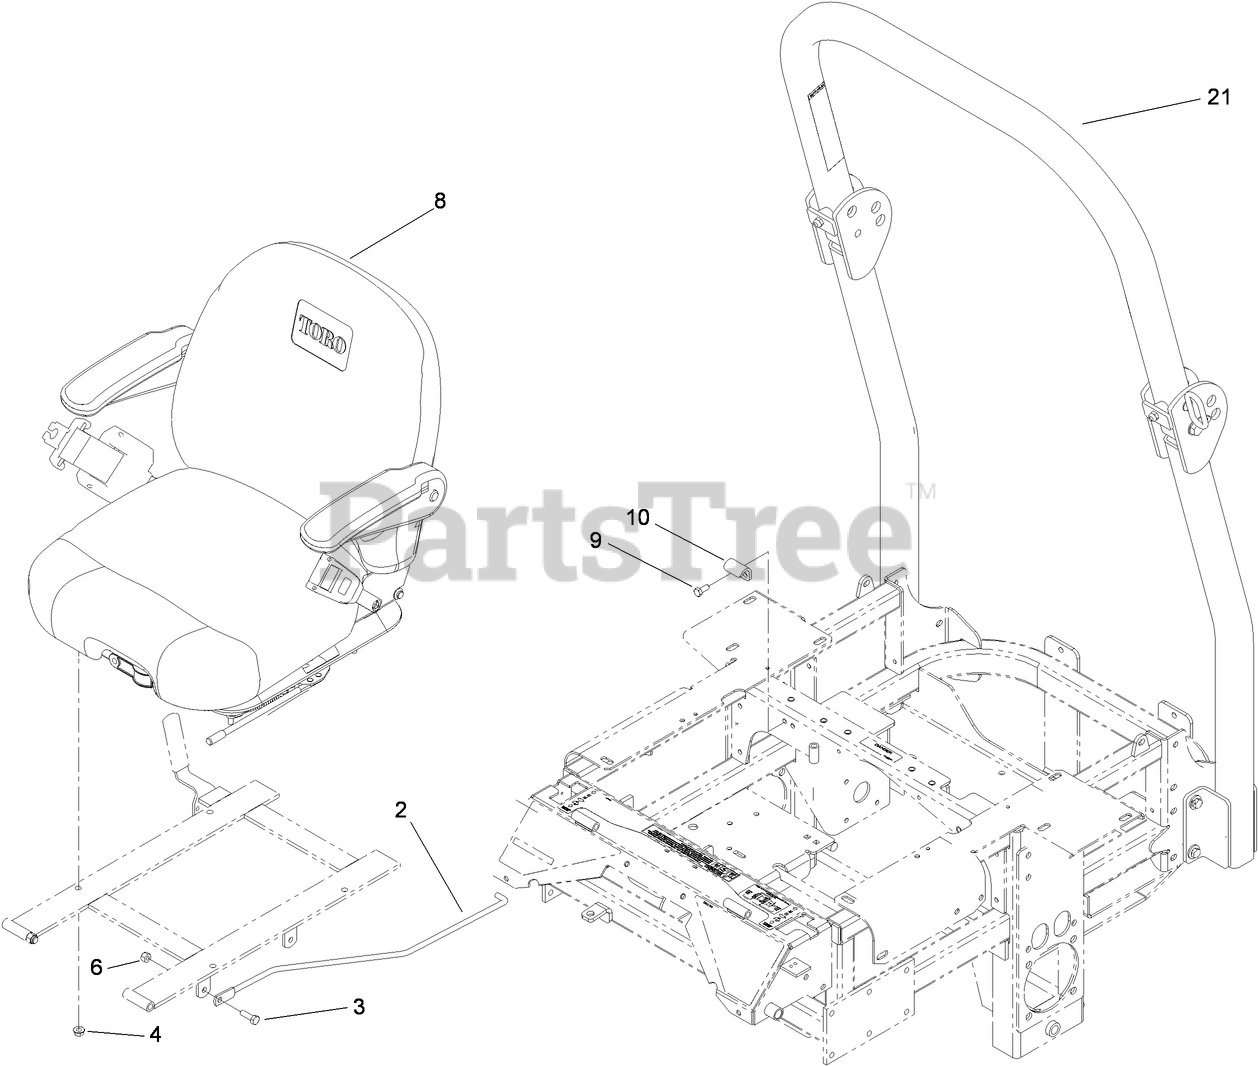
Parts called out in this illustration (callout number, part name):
2	ROD-PROP, SEAT
3	SCREW-HH
4	NUT-HF
6	NUT-LOCK, NI
8	DELUXE SEAT ASM
9	SCREW-HH
10	CATCH-LATCH, SEAT
21	ROPS KIT
